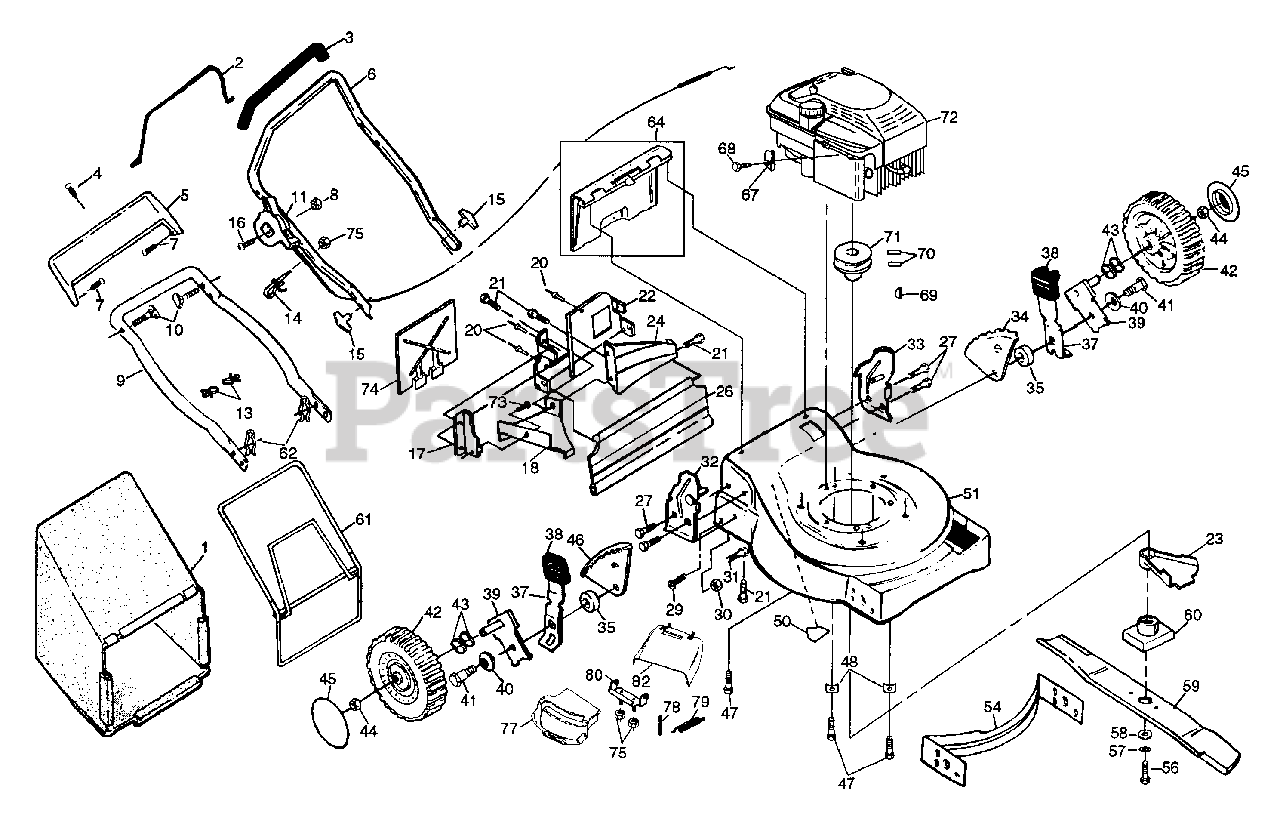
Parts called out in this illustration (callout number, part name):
1	Grass Bag Assembly
2	Control Bar
3	Handle Grip
5	Trim Plate
6	Upper Handle
7	Push-in Fastener
8	Locknut 1/4-20
9	Lower Handle
10	Handle Bolt
11	Throttle Control
13	Cable Clips
14	Rope Guide
15	Handle Knob
16	Round Head Screw 1/4-20 x 2-3/4
17	Side Baffle
18	Discharge Baffle
21	Hex Tapping Screw 1/4-20 x 1/2
22	Back Plate
23	Debris Shield
24	Rear Baffle
26	Rear Skirt
27	Thread Cutting Screw 5/16-18 x 3/4
29	Hinge Screw
30	Locknut
32	Handle Bracket Assembly (Right)
33	Handle Bracket Assembly (Left)
34	Wheel Adjusting Bracket (LR)
35	Spacer
37	Selector Spring
38	Selector Knob
39	Axle Arm Assembly
40	Belleville Washer
41	Shoulder Bolt 3/8-16
42	Wheel & Tire Assembly
43	Wave Washer
44	Nut
46	Wheel Adjusting Bracket (RR)
47	Thread Rolling Screw 3/8-16 x 1
48	Engine Washer
50	Danger Decal
51	Lawn Mower Housing
54	Front Baffle
56	Hex Head Screw 3/8-24 x 1-3/8 Gr. 8
57	Helical Lockwasher 3/8
58	Hardened Washer
60	Blade Adapter
61	Catcher Frame Assembly
62	Hairpin Cotter
64	Rear Door Assembly
67	Cable Clamp
68	Thread Rolling Screw #10-32 x 5/8
69	Hi-Pro Key
70	Set Screw 1/4-20 x 5/16
71	Engine Pulley
72	Engine - Briggs
74	Mulcher Plate
75	Nylon Locknut
77	Mulcher Door
79	Hinge Spring
80	Hinge Bracket
82	Clip-on Discharge Guard
